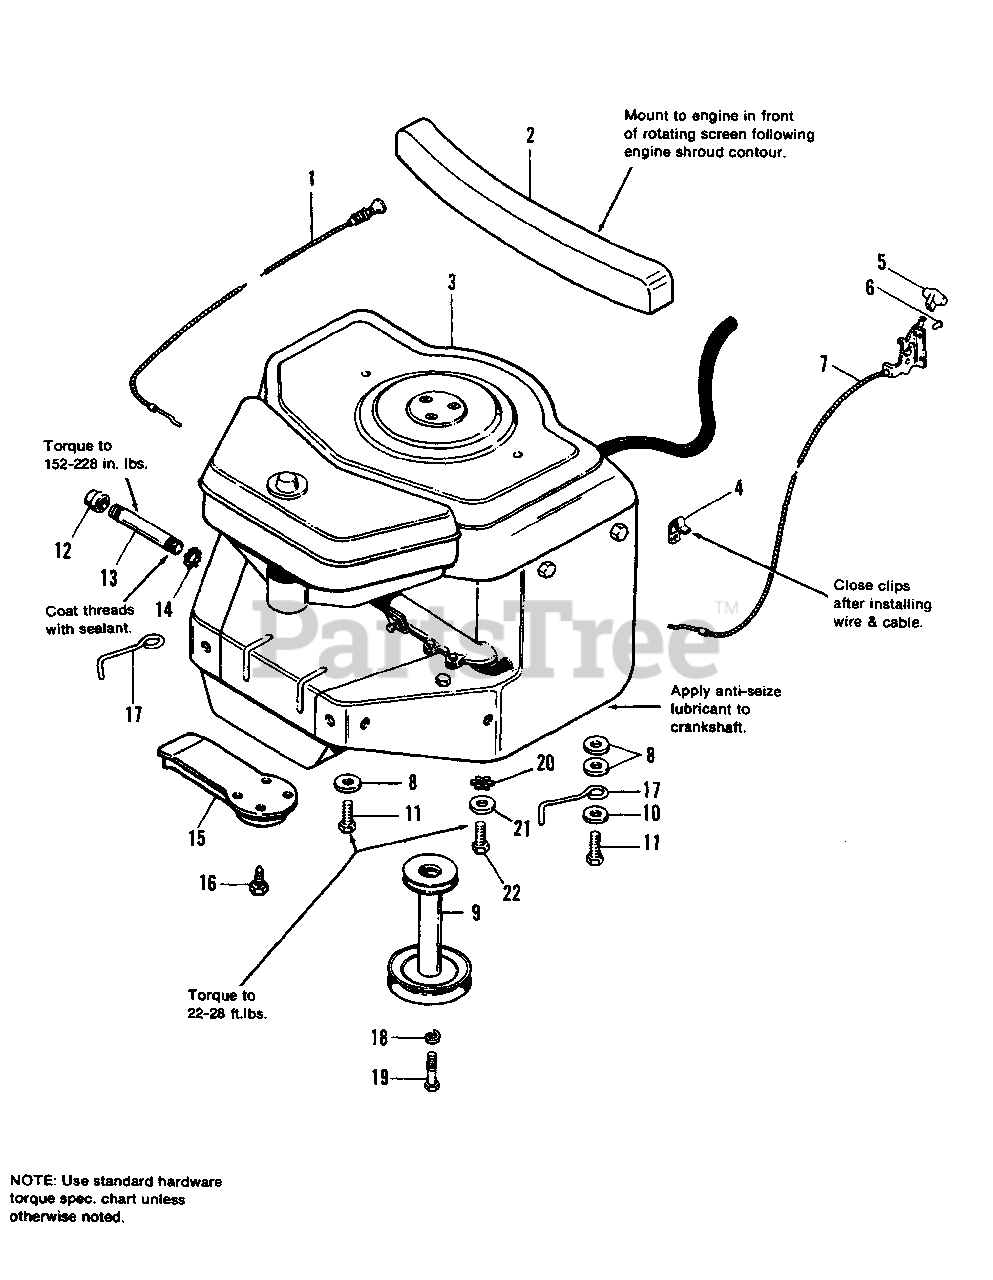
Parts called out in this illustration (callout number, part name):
1	CHOKE, w/Knob
2	BAFFLE, Engine, Rear
3	ENGINE ASSY., 16 HP ENGINE ASSY., 12.5 HP
4	CLAMP, Wire
5	KNOB, Throttle
7	THROTTLE CONTROL ASSY.
8	WASHER
9	PULLEY ASSY., Engine
10	WASHER, Plain, 3/8
11	SCREW, Taptite, 3/8-16 x 1-1/2
12	PIPE, Cap, Hex
13	PIPE, Oil Drain
14	LOCKNUT, Conduit, 3/8
15	EXTENSION ASSY., Muffler
16	SCREW, Hex, Thd. Cutting, #8-32 x 3/8
17	STOP, Belt, Engine
18	LOCKWASHER, 7/16
19	CAPSCREW, 7/16-20 x 1-1/4
20	LOCKWASHER, Ext. Tooth (Zinc Pltd.)
21	WASHER, Plain, 3/8 (Zinc Pltd.)
22	CAPSCREW, 3/8-16 x 1
